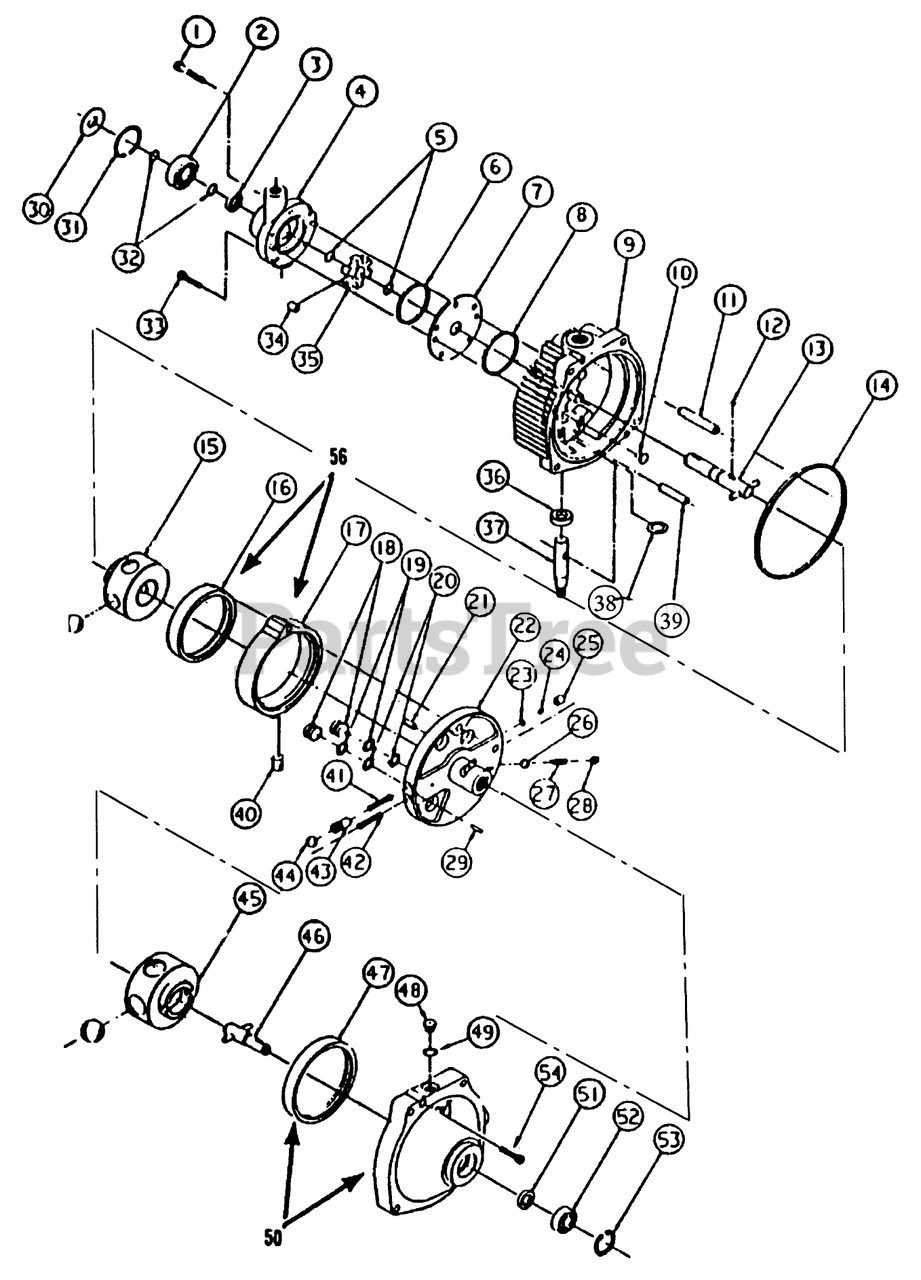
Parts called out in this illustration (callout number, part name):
9	COVER SUB ASM
11	Pin-Pivot
16	PUMP-RACE
17	Ring-Cam
19	Ring-Back Up
20	"O" Ring
30	SHIELD-GRASS
31	RETAINING-RING
38	Washer
39	Dowl
47	Race-Motor
51	Seal ASM
